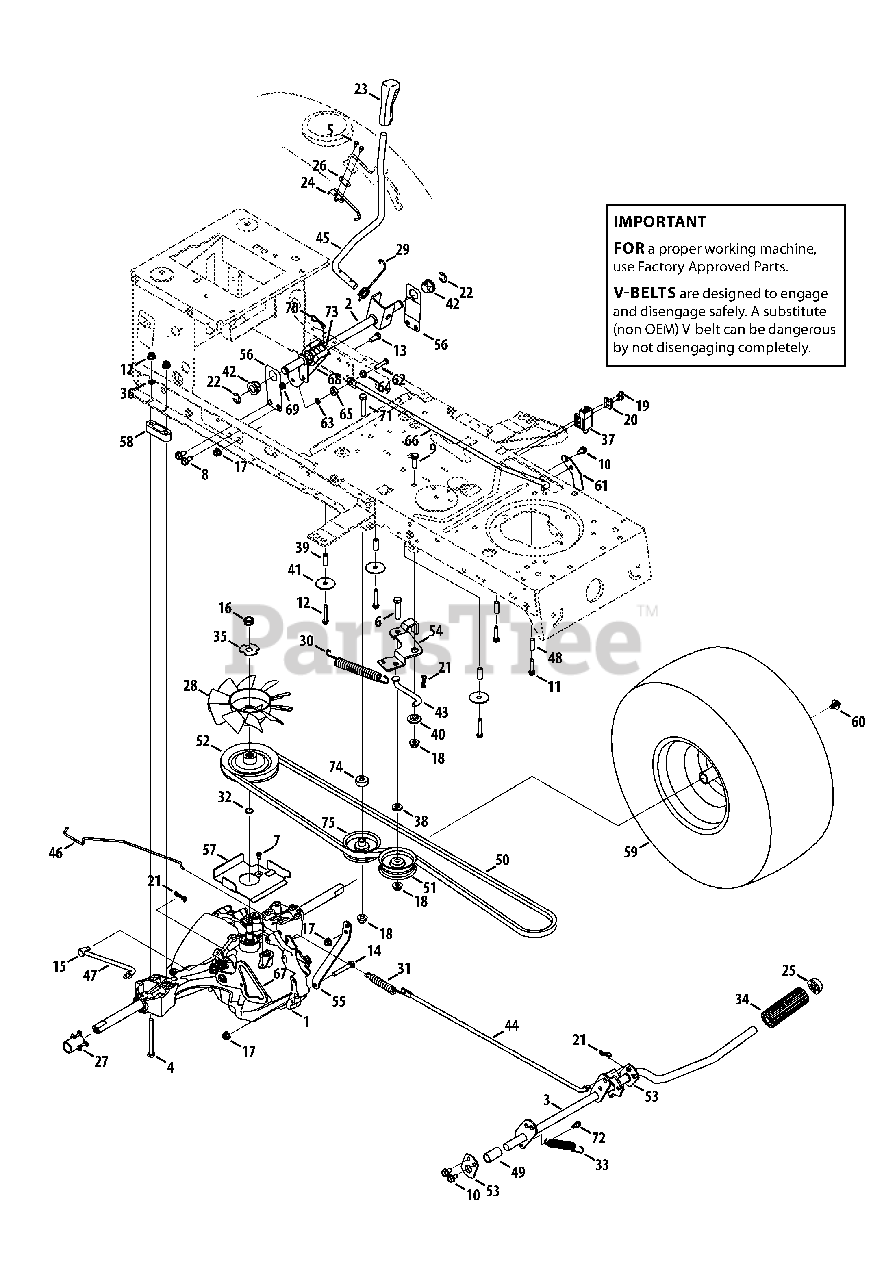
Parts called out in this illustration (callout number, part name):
1	Hydro Transmission
2	Hydro Handle Control Assembly
3	Hydro Pedal Assembly
4	Hex Screw, 5/16-18 x 3.5
5	Screw, #8-18x0.500
6	Hex Screw, 3/8-16x1.75
7	Screw, #10-16x0.500
8	Screw, 5/16-18x.750
9	Hex Screw, 3/8-16x1.00
10	Screw, 5/16-18x0.625
11	Screw, 1/4-20x1.250
12	Screw, 1/4-20 x 1.75
13	Hex Screw, 5/16-18x.75
14	Screw, 5/16-18 x 2.00
15	Ferrule, 5/16-24 X .312 DIA.
16	Jamlock Nut, 1/2-20
17	Flangelock Nut, 5/16-18
18	Flangelock Nut, 3/8-16
20	Plate Switch
21	Cotter Pin, Bow Tie
22	E Rign, .625 DIA
23	Handle Grip
24	Hydro Spring Switch
25	Push Cap, 5/8
26	Insulator Plate Nut
27	Sleeve, .765 ID X 2.11 LG
29	Torsion Spring
30	Extension Spring, .75 DIA. X 6.02
31	Extension Spring, .59 OD X 4.00 LG
32	Wire Ring
33	Extension Spring, .63 DIA X 4.95 LG
34	Foot Pad, 4.0
35	Lock Washer, TRANS HYDRO
36	Lock Washer, 5/16 EXT TOOTH
37	Switch Interlock
38	Flat Washer, .407X.812X.135:HT
39	Spacer, .260 x .372 x 1.420
40	Shldr Spacer, 1.375 ID X .380 x 1.54
41	Flat Washer, .350 x 1.59 x .062
42	Hex Flange Bearing
43	Declutching Rod
44	Brake Rod
45	Hydro Control Handle
46	Hydro Bypass Rod
47	Hydro Control Rod
48	Spacer, .260 x .375 x 1.030 LG
49	Spacer, .640 ID X .76 OD X 1.60
50	V Belt, 4L SEC X 84.17
51	Flat Idler Pulley 2.75 OD
52	Input Pulley
53	Support Pedal Bracket
55	Torque Bracket
56	Handle Bracket
57	Belt Support Bracket
58	Spacer, T-Axle
59	Wheel, 20 x 8 x 8 - Grey
60	Screw, 5/16-24 x .750
61	Stop Pedal Plate
62	Hex Screw, 1/4-20 x 1.25
63	Flat Washer, .281 x .500 x .063
64	Shoulder Spacer, .375 x .625 x .20
65	Ball Bearing, .25 x .6875 x .25
66	Hydro Rod, RTN
67	Cam Bracket, RTN
68	Pivot Bracket, RTN
69	Nut, Flange Lock, 1/4-20, GrF
70	Click Pin, .092 x 1.64 LG
71	Hex Screw, 3/8-16 x 2.00
72	Shoulder Screw, 1/4-20 x 0.50
73	Hex Flange Bearing, .628 ID
74	Spacer, .406 ID x 1.00 OD x .38
75	V Pulley 3.06 OD
